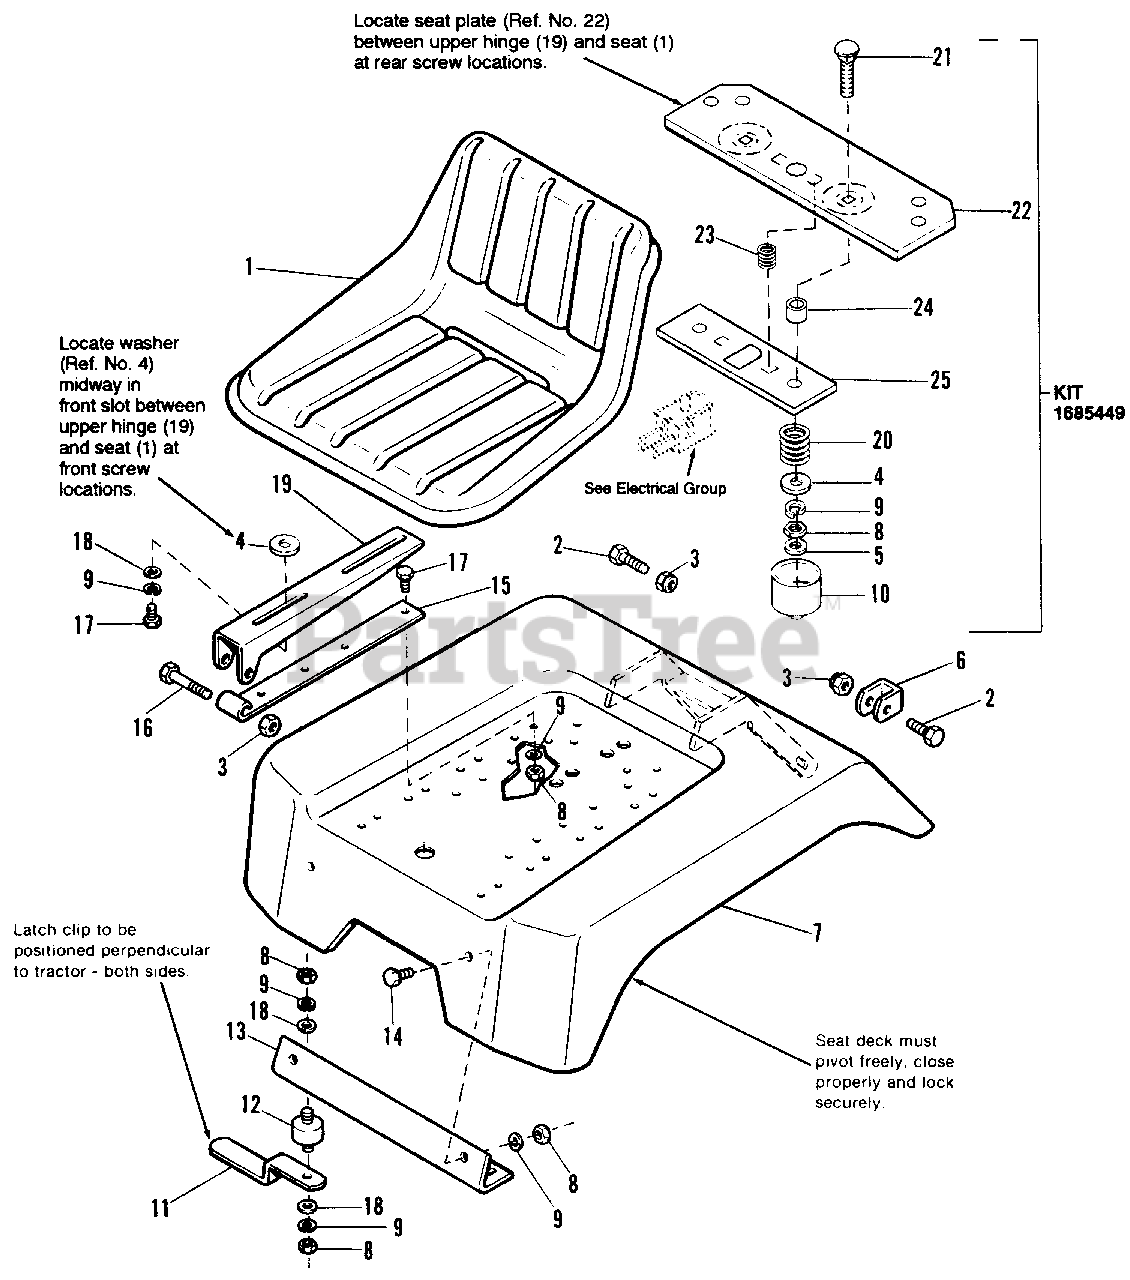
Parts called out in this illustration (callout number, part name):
2	CAPSCREW, Hex Hd., 3/8-16x1-1/4
3	LOCKNUT, Hex, 3/8-16
6	STOP, Seat Deck
7	DECKASSY., Seat
8	NUT, Hex, Full, 5/16-18
9	LOCKWASHER, 5/16
10	COVER, Spring
12	CONNECTOR, Cushion
13	BRACKET, Seat Deck, Front
14	APSCREW, Hex Hd, 5/16-18x5/8
15	HINGE, Lower
16	CAPSCREW, Hex Hd., 3/8-16 x 2
17	CAPSCREW, Hex Hd., 5/16-18x3/4
18	WASHER, Plain, 5/16
19	HINGE, Upper
21	CARRIAGE BOLT, 5/16-18x 1-1/2
22	PLATE, Seat
25	PLATE, Switch
